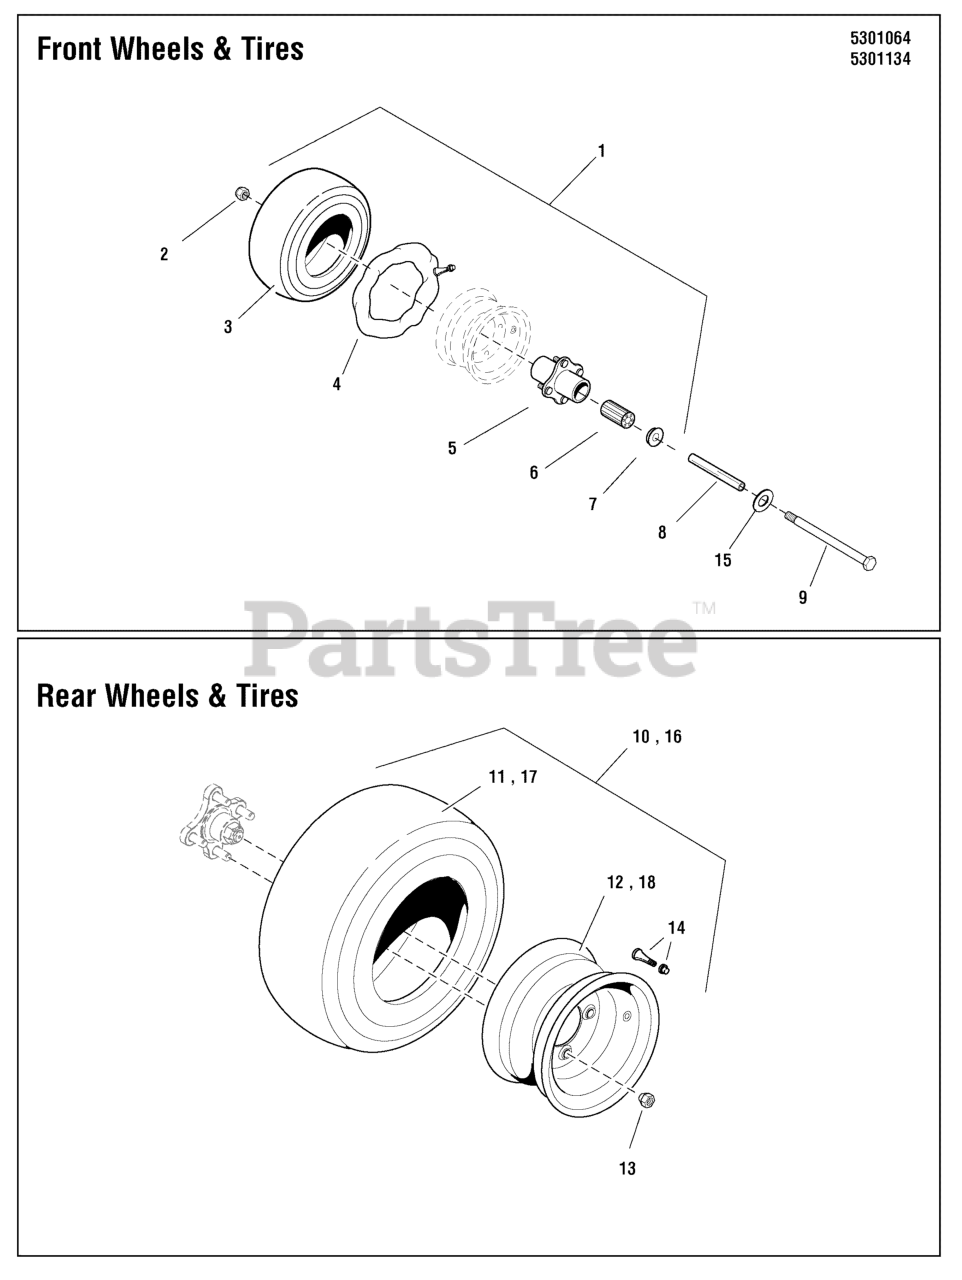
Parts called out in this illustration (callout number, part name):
1	TIRE ASSM, 9 X 3.5 X 4, SILVER
2	NUT, Hex Flange, Nylock, 1/2-13
3	TIRE, FRONT 9 X 3.5 X 4 (SV)
5	HUB & BEARING ASSEMBLY (SV)
6	BEARING, ROLLER 3/4" ID X 3.25" (ONE PER TIRE)(SV)
7	RETAINER, BEARING (TWO PER TIRE)(SV)
8	AXLE, CASTER WHEEL
9	BOLT, 1/2-13 X 5-1/2" GD5 YZ
10	TIRE ASM, 18 X 6.50-8, 4 PLY K500
11	TIRE, 18 X 6.5 - 8, MULTI-TRAC (SV)
12	RIM, 8 X 5.375 4L 2.82 CH POS SILVER (SV)
13	NUT, 1/2-20, FOR WHEEL BOLT SILVER
14	VALVE STEM, SNAP IN (SV)
15	WASHER, 1/2 SAE
16	TIRE, 18 X 8.5 X 8, 4 PLY
17	TIRE ONLY (SV)
18	WHEEL ONLY (SV)
